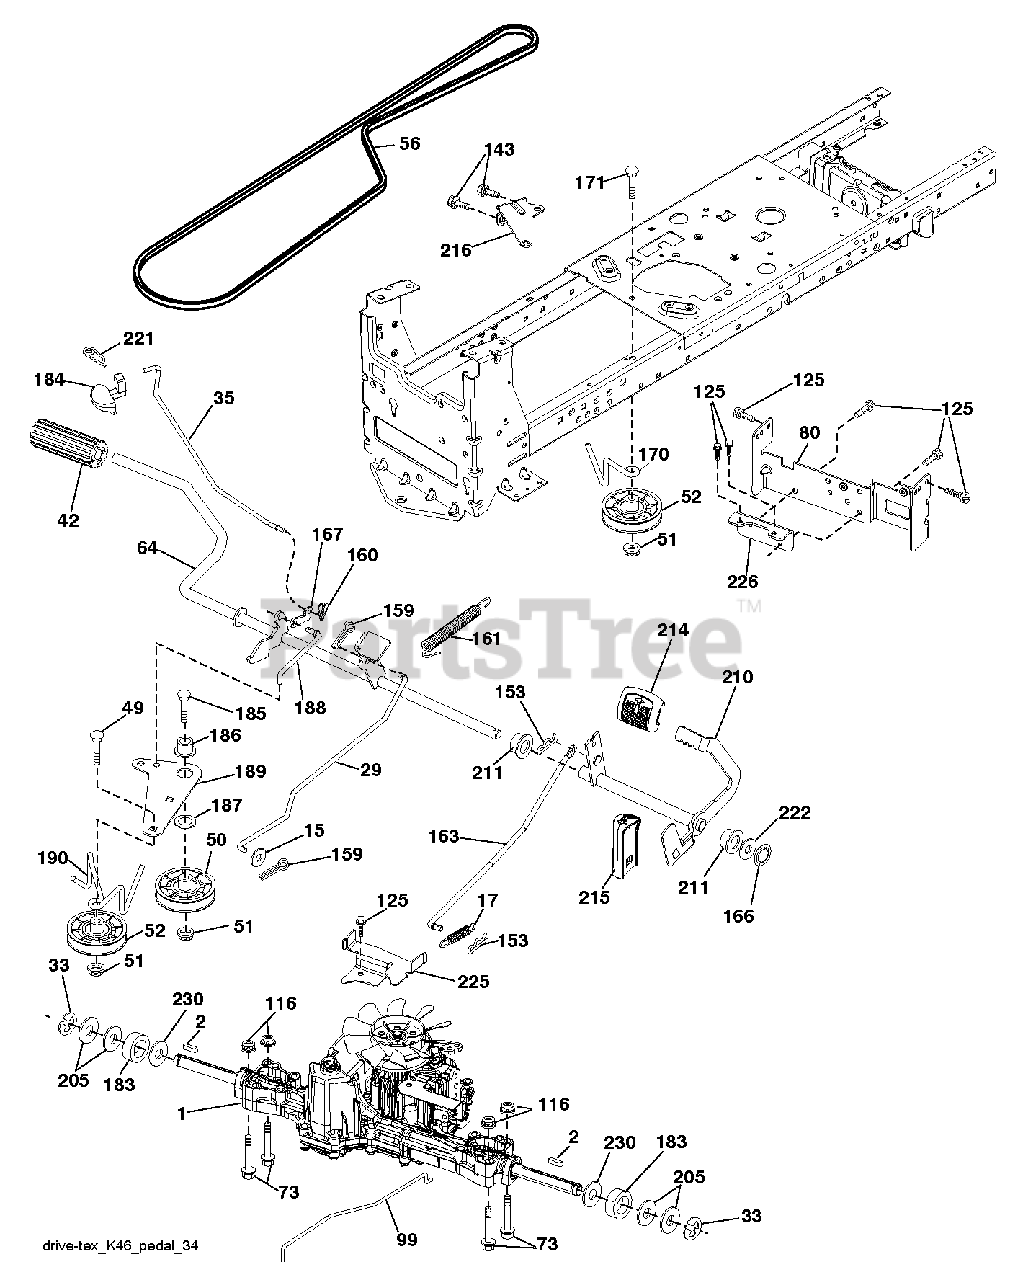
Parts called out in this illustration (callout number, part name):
2	SQUARE KEY
15	WASHER
17	SPRING.BRAKE.K46.GREEN
29	ROD.BRAKE.K46
35	ROD.CNTRL.PARK.PREDATOR.LT.TEX
42	PEDAL COVER T
50	IDLER.FLAT.910.OFFSET
51	NUT LOCK FLG 3/8-16 UNC
52	IDLER.V-GROOVE.910.OFFSET
56	V-BELT.MOWER.92.40.42/K46
64	SHAFT.ASM.PEDAL.BRK.CNTR
80	STRAP.TORQUE.K46.K57R.TT
99	ROD.SPRING.BYPASS.K46.LT.Z
116	NUT LOCK HEX FLANGE 5/16-18
125	SCREW
143	SCREW LT
153	RETAINER M
159	COTTER PIN
160	RETAINER CLIP
161	SPRING, RETURN LT
163	ROD.CONTROL.K57R.K46
166	NUT.PUSH.625
167	LATCH.BRAKE.SPRING
170	KEEPER.V-IDLER.CENTER.
183	SPACER AXLE
184	HANDLE.PARKING.BRK.PRED.LT.RED
186	SPACER.RETAINER
187	WASHER 12/32X2X10GA
188	RP LINK.CLUTCH.GROUND.DRIVE
189	BELLCRANK.GROUND.DRIVE.TEX.
190	KEEPER.BELLCRANK.DRIVE
210	ROCKER.ASM.PEDAL.CONTR
211	BEARING.NYLON
214	PEDAL.FORWARD.PAD.TEX
215	PEDAL.REVERSE.TEX.GT.4
216	BRACKET.PULLEY.IDLER.W/TEX
221	RETAINER.SPRING.CLIP.H
222	WASHER 21/32 X 1-1/4 X 10 GA.
225	KEEPER.BELT.TRANSAXLE.K46
226	BRACKET.MOUNT.TORQUE.K46.TLT
230	WASHER.HARDENED
